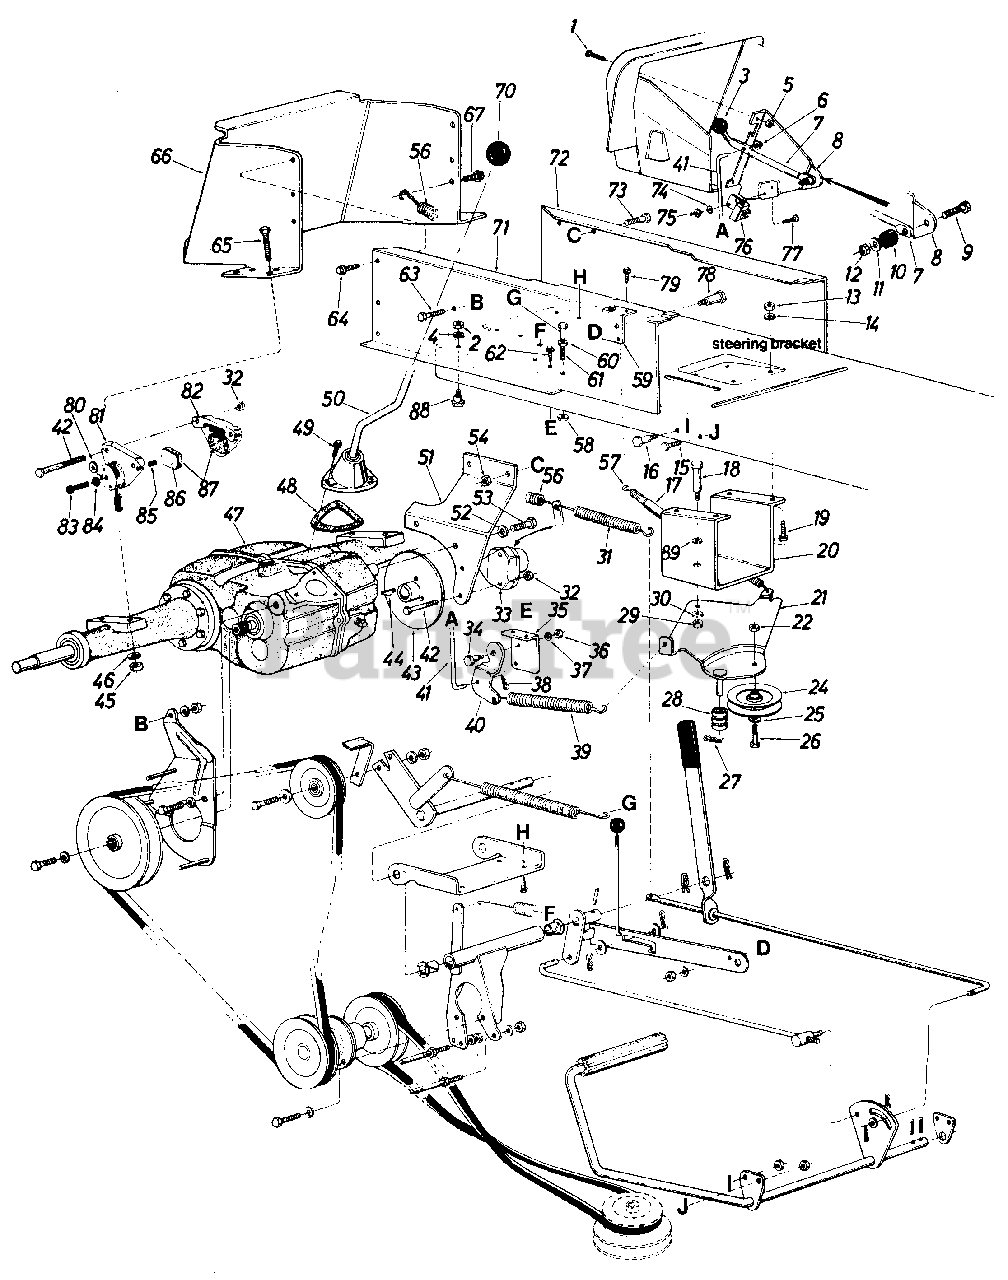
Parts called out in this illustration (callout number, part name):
1	Truss Mach. Scr. 1/4-20 x .50" Lg.
2	Hex Nut 1/4-20 Thd.
3	Knob-Blade Clutch
4	L-Wash. 1/4 I.D.
5	Hex Sems Nut 1/4-20 Thd.
6	Push Cap 1/4n Rod
7	Blade Clutch Lever
8	Deck Clutch Control Brkt.
9	Hex Scr. 1/4-20 x 1.25" Lg.
10	Rubber Wash. .330 I.D. x .87
11	Fl-Wash. 1/4" I.D. x .75" O.D. x .057
12	Hex Cent. L-Nut 1/4-20 Thd.
13	Hex Nut 5/16-18 Thd.
14	L-Wash. 5/16" I.D.
15	Hex Bolt 3/8-16 x .62" Lg.
16	Shld. Bolt 1/2" Dia. x .335 Lg. 3/8-16
17	Convoluted Conduit .50 I.D. x 4" Lg.
18	Shld. Bolt 7/16 Dia. x .16" 5/1 6-1 8
19	Hex Bolt 5/16-18 x 1.00" Lg.'
20	Idler Mtg. Brkt.-Deck
21	Idler Brkt. Ass'y.
22	Hex L-Nut 3/8-16 Thd.
24	4"-"V" Idler Pulley
25	Fl-Wash. 3/8" I.D.
26	Hex Bolt 3/8-16 x 1.25" Lg.
27	Hairpin Cotter 5/16" Rod
28	Spacer
29	Hex Nut 5/16-18 Thd.
30	L-Wash. 5/16" Scr.
31	Ext. Spring-Brake Rod
32	Hex Cent. L-Nut 3/8-16 Thd.
33	Disc Brake Caliper Ass'y.
34	Shld. Scr. 7/16" Dia. x .16" Lg. 5/16-18
35	Parking Brake Cam Mtg. Brkt.
36	Hex Nut 5/16-18 Thd.
37	L-Wash. 5/16" I.D.
38	Hairpin Cotter 5/16" Dia.
39	Ext. Spring-Deck Control
40	Deck Control Pivot Brkt.
41	Deck Control Rod
42	Hex Bolt 3/8-16 x 2.50" Lg.
43	Hub & Disc Ass'y. (For Brake)
44	Hi-Pro Key 3/16 x 3/4" Lg.
45	Hex Nut 3/8-16 Thd.
46	L-Wash. 3/8" I.D.
47	Transaxle
51	Transaxle Support
52	L-Wash. 3/8" Scr.
53	Hex Scr. 3/8-16 x .75" Lg.
54	Hex L-Nut 3/8-16 Thd.
56	Ext. Spring-Brake Return
57	Ext. Spring-Deck Idler Return
58	Hex L-Nut 5/16-18 Thd.
59	Parking Brake Cam Mtg. Brkt.
60	Hex Nut 5/16-18 Thd.
61	Hex Bolt 5/16-18 x 1.5" Lg.
62	Hex Thd. Rolling Scr. 1/4-20 x.50" Lg.
63	Hex Bolt 3/8-16 x .75" Lg.
64	Hex AB-Tap Scr. 5/16 x .75" Lg.
65	Hex Scr. 3/8-16 x 1.50" Lg.
66	Hitch Plate
67	Hex Thd. Rolling Scr. 5/16-24 x .75" Lg.
70	Knob-Transaxle
71	Side Panel Upper Frame-R.H.
72	Side Panel Upper Frame-L.H.
73	Hex Bolt 3/8-16 x .75" Lg.
75	Hex Nut #10-24 Thd.
76	Safety Switch (Deck)
77	Truss Mach. Scr. #10-24 x .50" Lg.
78	Shld. Bolt 7/16" Dia. x .16" Lg. 5/16-18
79	Hex Thd. Rolling Scr. 1/4-20 x.50" Lg.
80	Washer
81	Housing with Lever & Pin
82	Anvil
83	Pin, Adjuster
85	Pin, Actuator
86	Backing Plate
87	Lining
88	Shld. Bolt .375" Dia. x .180 Lg. 1/4-20 Thd.
89	Wave Washer
